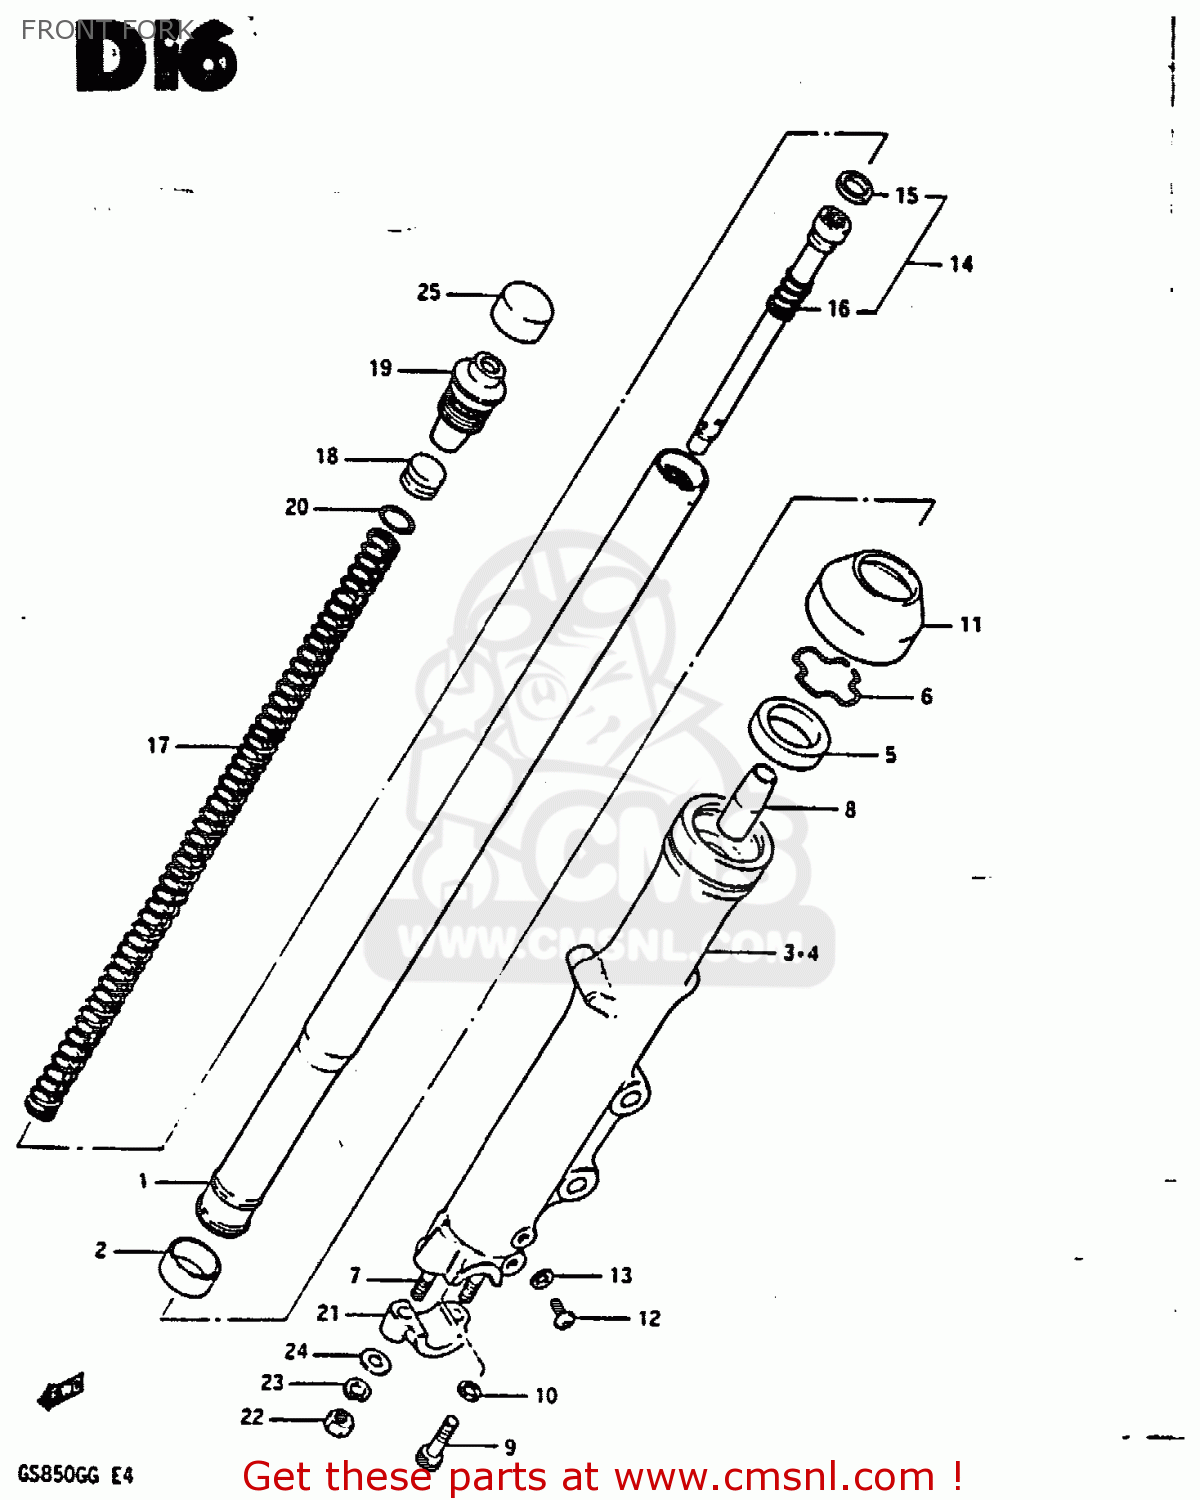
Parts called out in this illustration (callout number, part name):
1	TUBE,FORK,INNER
2	PISTON
3	TUBE,FORK,OUTER,RIGHT
4	TUBE,FORK,LEFT,OUTER
5	OIL SEAL,FRONT FORK
6	RING,STOPPER
7	BOLT,STUD
8	PIECE,OIL LOCK
9	BOLT,FORK CYLINDER(10X25)
10	GASKET (NAS)
11	SEAL,DUST
12	SCREW
13	GASKET,DRAIN,PLUG (NAS)
14	CYLINDER,FRONT FORK
15	RING,PISTON
16	SPRING,REBOUND
17	SPRING,FRONT FORK
18	PISTON,FREE
19	CAP
20	O-RING
21	HOLDER,AXLE
22	NUT (8MM)
23	LOCK WASHER
24	WASHER
25	CAP,RUBBER
